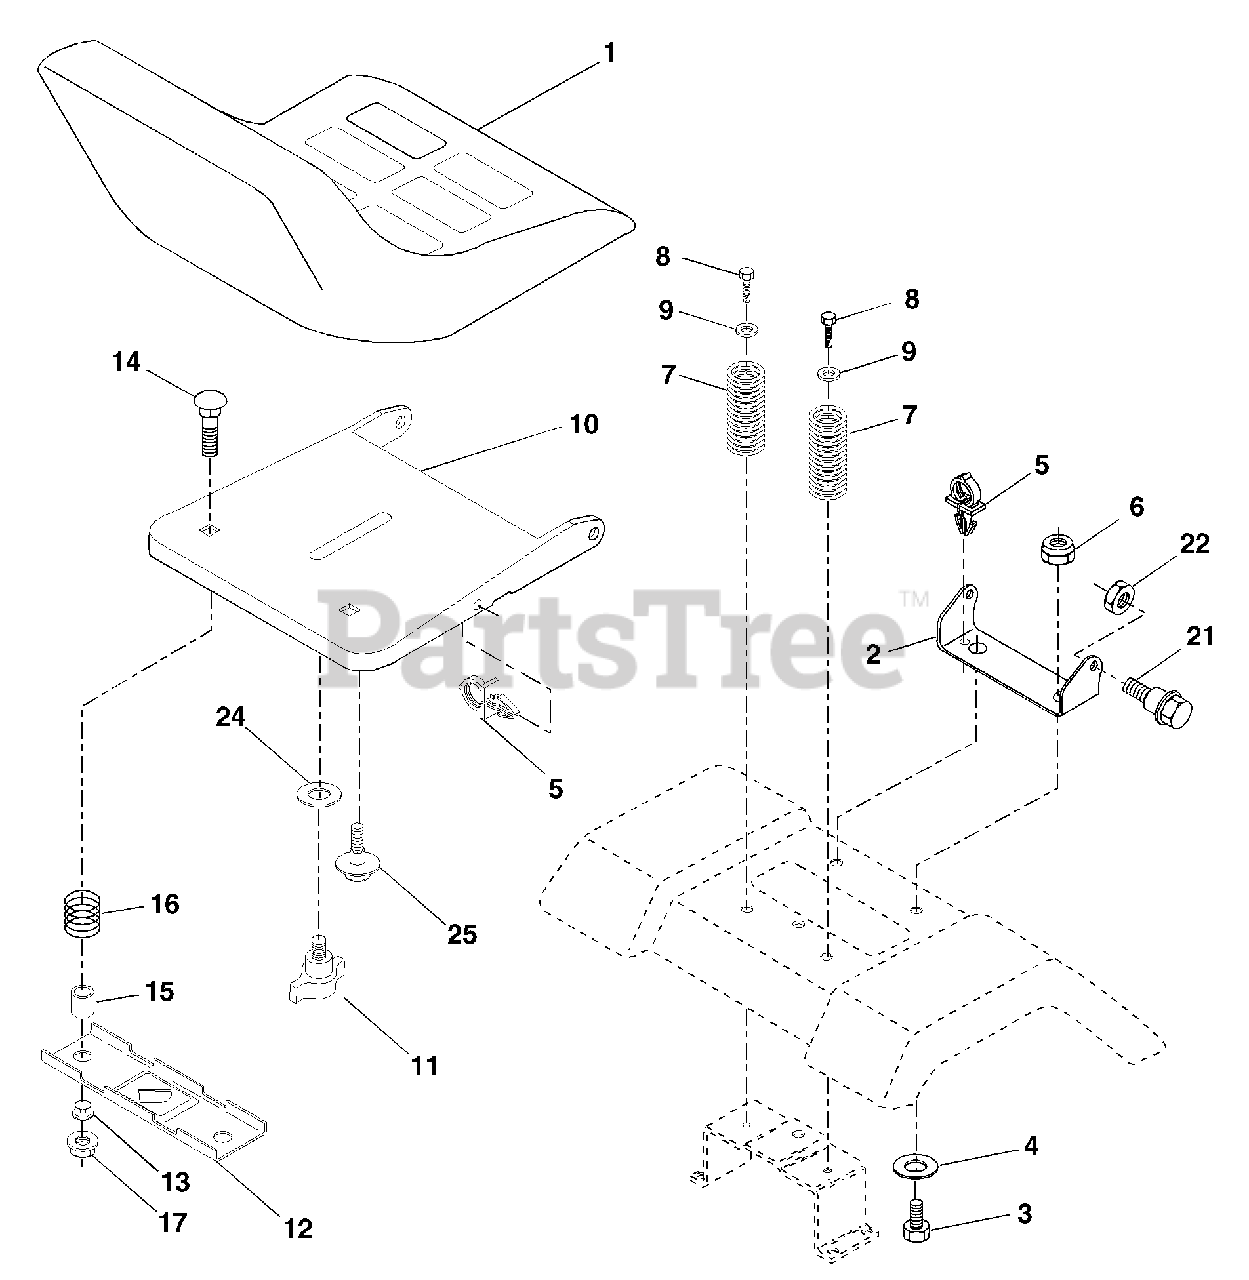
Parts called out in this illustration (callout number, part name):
1	Seat
2	Bracket Pivot Seat 8 720
3	Bolt Fin Hex 3/8-16unc X 1
4	Washer 13/32 X 1 X 10 Ga
5	Clip Push-In
6	Nut Hex w/Ins. 3/8-16 Unc
7	Spring Seat Cprsn 2 250 Blk Zi
8	Screw 3/8-16 x 1.5 Smgml
9	Washer 13/32 X 1 X 14 Ga.
10	Pan Seat
11	Knob Seat
12	Bracket Mounting Switch
13	Bushing Snap Blk Nyl 50 Id
14	Bolt Rdhd Sqnk 1/4-20x1-1/2
15	Spacer Split 28x 88
16	Spring Cprsn
17	Nut Lock 1/4 Lge Flg Gr 5 Zinc
21	Bolt Shoulder 5/16-18 Unc
22	Nut Hex Lock W/Ins 5/16-18
24	Washer 17/32 X 1-3/16 X 12 Ga.
25	Bolt Shoulder 5/16-18 X 62
